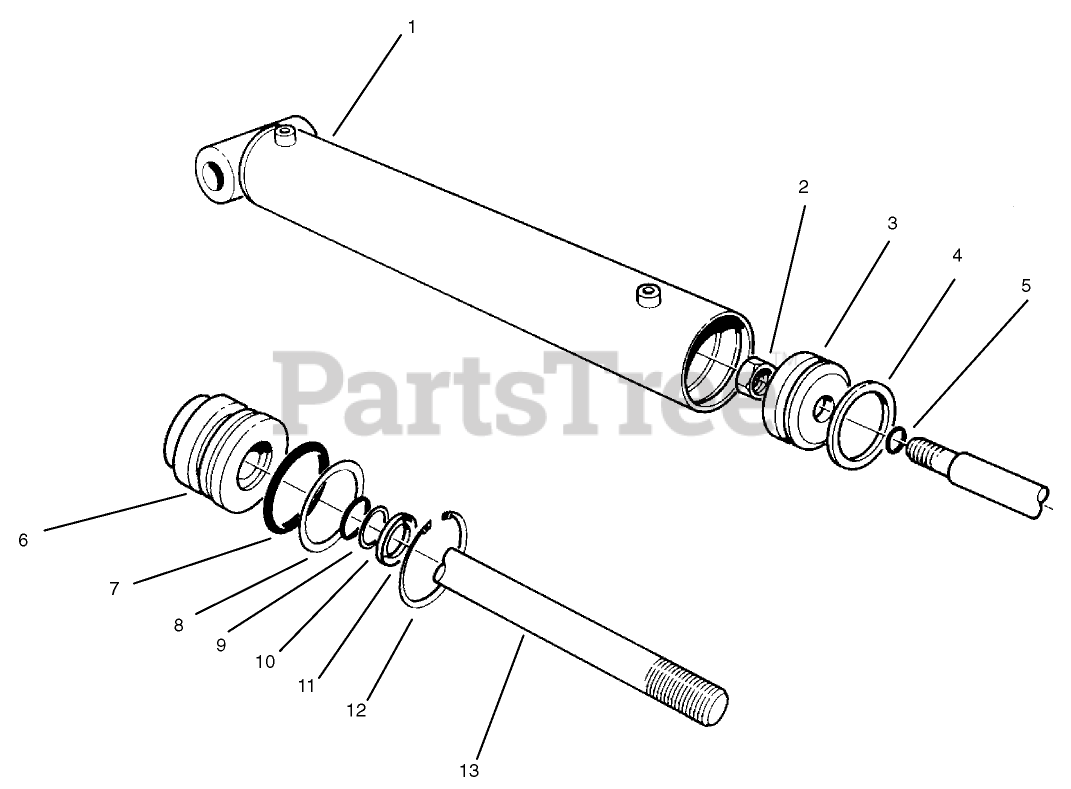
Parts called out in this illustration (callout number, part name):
1	Barrel
2	LOCKNUT
3	PISTON
4	Uniring
5	Seal-Dust
7	Seal-Dust
8	Washer-Backup
9	Seal-Dust
10	Washer-Backup
11	Seal-Dust
12	RING-RETAINING
13	SHAFT
